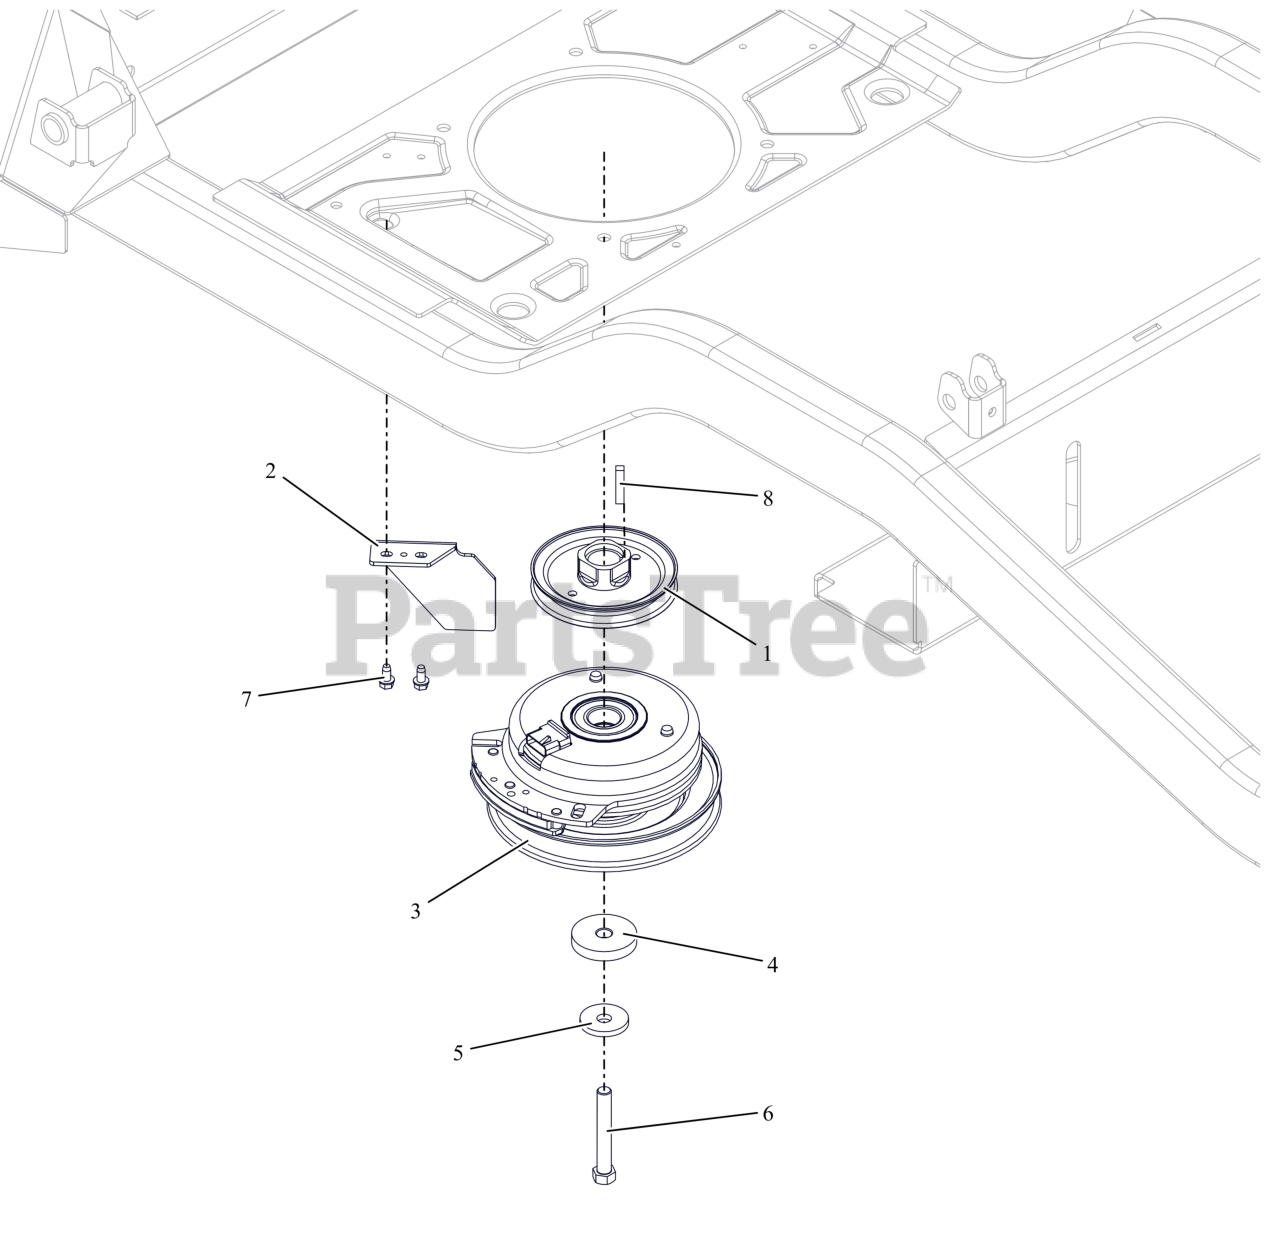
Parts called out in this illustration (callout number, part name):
1	PULLEY, 4.50 OD X 1.003 ENGINE
2	BRKT, CLUTCH
3	CLUTCH, WARNER 1.00 HD,PTZ
4	SPACER, .474/.459X2.00X.350
5	WASHER, 7/16" SPRING DISK
6	BLT, HEX .44-20X3.00 G8 ZCC NT
7	SCR-TAP .25-20X.50 HWH ZCC
8	KEY-SQ .25 X 1.25 X .25 SAE
